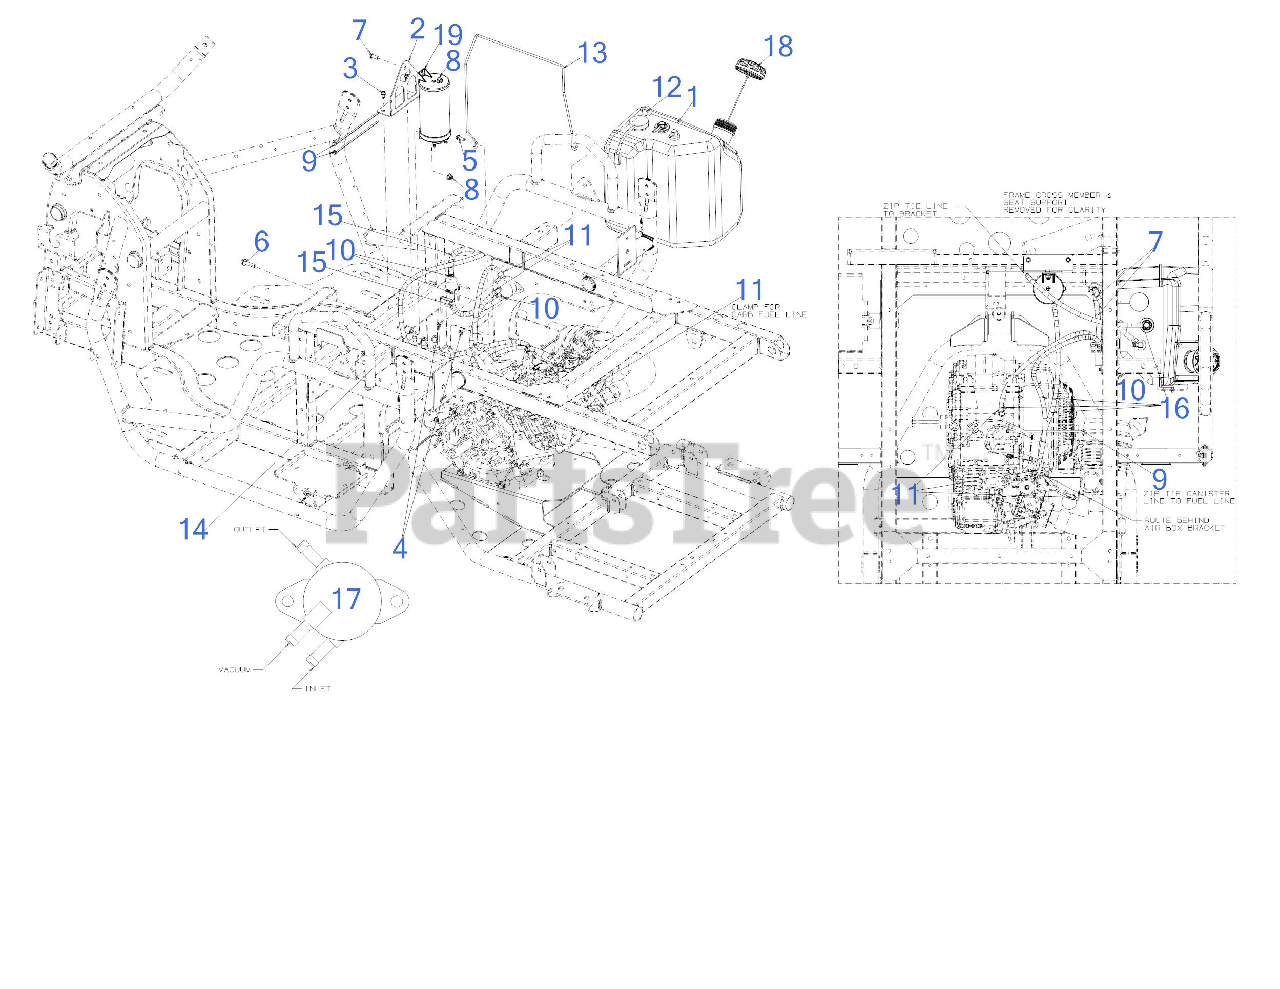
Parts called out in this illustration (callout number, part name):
1	FUEL TANK ASSEMBLY
2	CARBON CANISTER MOUNTING BRACKET
3	SCREW 1/4-20 X.500
4	SCREW M6-1 x .625
5	SCREW 1/4-20 x .750
6	SCREW 5/16-18 x 1.25 GR5
7	SCREW 5/16-18 x .75 GR5
8	FLANGE LOCK NUT 5/16-18
9	7" CABLE TIE
10	HOSE CLAMP 1/20
11	HOSE CLAMP 0.470
12	RUBBER BUMPER 1.000 x .313
13	FUEL TANK RETENTION ROD
14	SPACER .34 x .75 x .63 LG
15	FUEL HOSE LOW PERMEATION
16	FUEL HOSE LO PERMEATION 7/32 YELLOW
17	ENGINE FUEL PUMP
18	FUEL CAP W/TETHER
19	CARBON CANISTER
